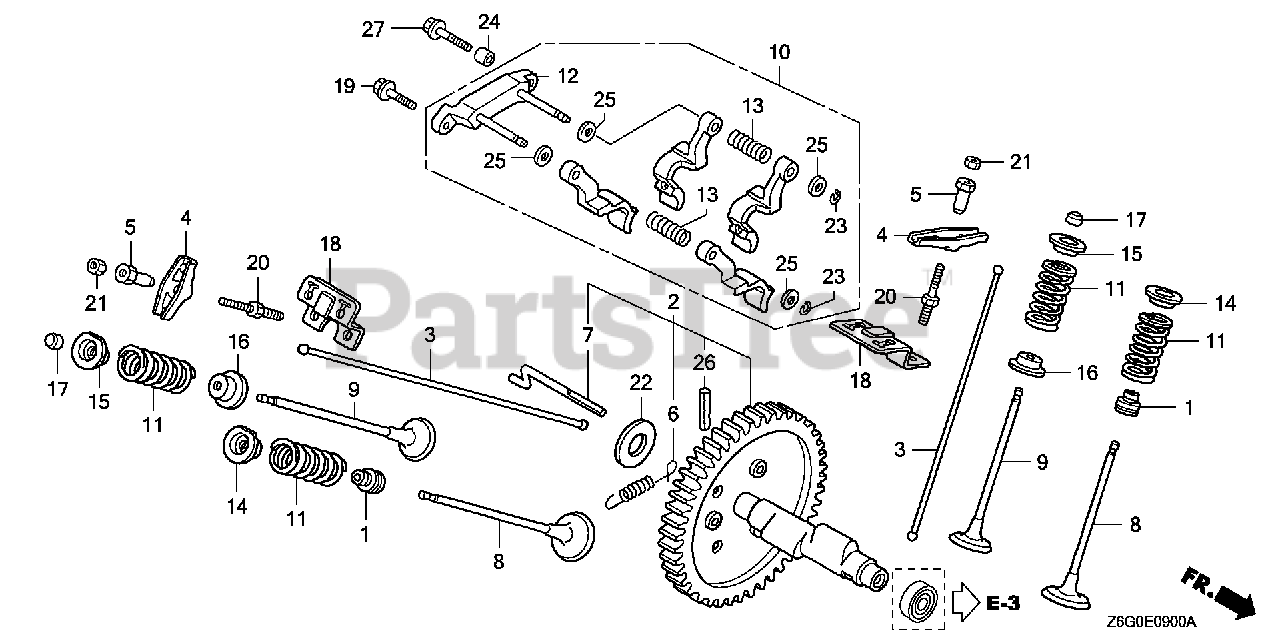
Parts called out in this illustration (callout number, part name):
1	SEAL, VALVE STEM
2	CAMSHAFT ASSY.
3	ROD, PUSH
4	ARM, VALVE ROCKER
5	PIVOT, ROCKER ARM
6	SPRING, WEIGHT RETURN
7	PIN, DECOMPRESSION
8	VALVE, IN.
9	VALVE, EX.
10	LIFTER ASSY., VALVE
11	SPRING, VALVE
12	SHAFT, VALVE LIFTER
13	SPRING, VALVE LIFTER
14	RETAINER, IN. VALVE SPRING (EXHAUST SIDE)
15	RETAINER, EX. VALVE SPRING
16	SEAT, VALVE SPRING
17	ROTATOR, VALVE
18	PLATE, PUSH ROD GUIDE
19	BOLT, FLANGE (5X16)
20	BOLT, PIVOT (8MM)
21	NUT, PIVOT ADJ.
22	WASHER, THRUST (17.2MM)
23	CLIP, GOVERNOR HOLDER
24	PIN A, DOWEL (8X12)
25	WASHER, PLAIN (6MM)
26	PIN, SPRING (6X28)
27	BOLT, FLANGE (6X25)
